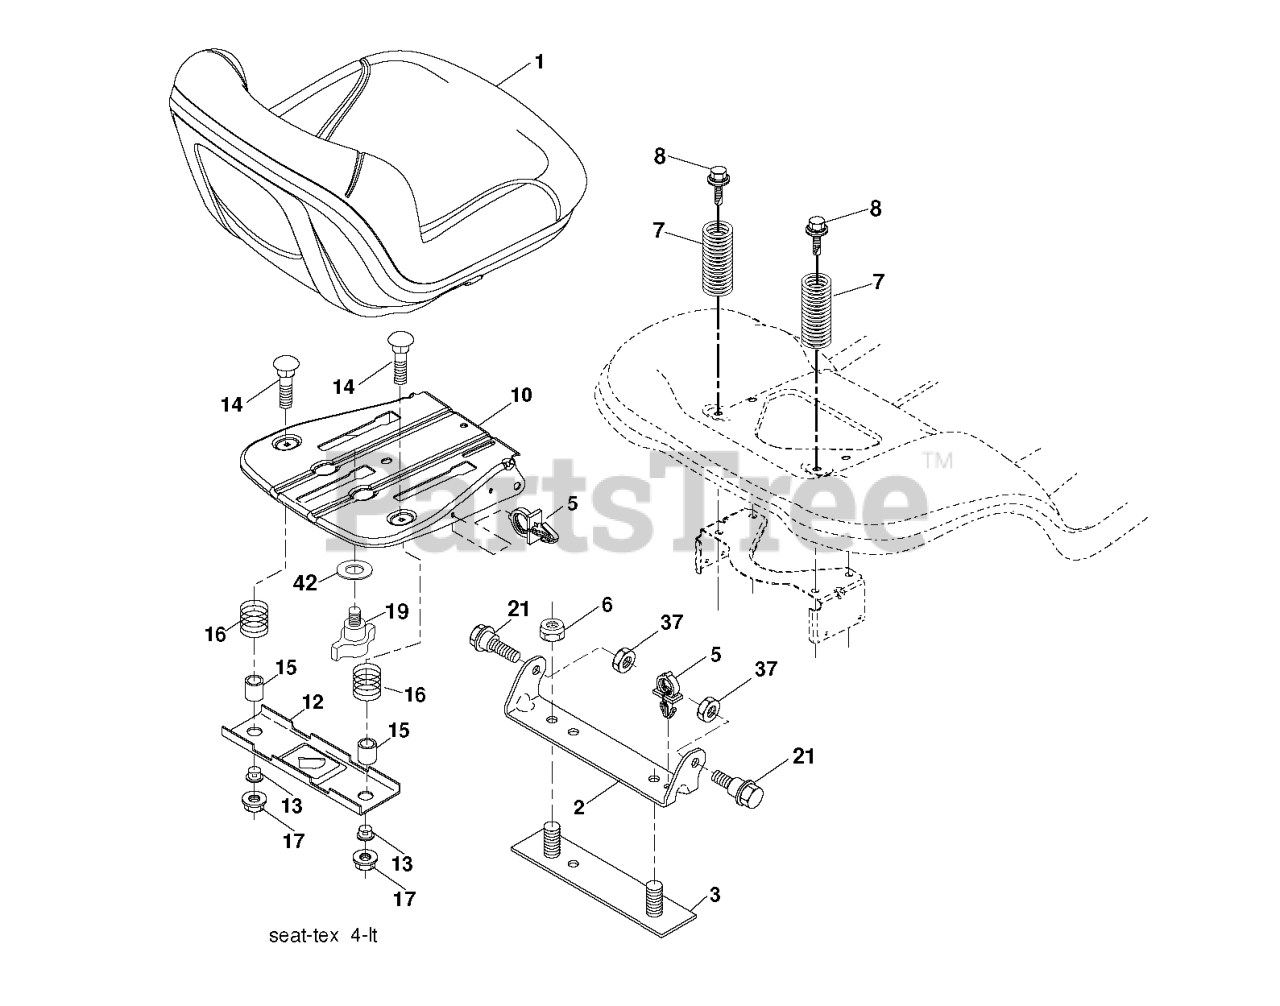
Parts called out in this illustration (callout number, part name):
1	SEAT.TH130.GRY.MILSCO.
2	BRKT.PIVOT.FENDER
3	STRAP
6	NUT
7	SPRING COMPRESSION
8	BOLT.5/16-18UNCX3/4 W/SEMS.BLK
10	PAN.ASM.SEAT.SHORT
12	BRKT.MNT.OPC.SW.SEAT.
14	BOLT.ROUND.HEAD.SQUARE.NECK
15	SPACER SPLIT 28X.96
16	SPRING COMPRESSED
17	NUT T
19	KNOB.SEAT.ADJ.
21	BOLT.SHOULDER.5/16-18
37	NUT.71038.31-18.HEX.NYLOCK
42	WASHER.CUP.SEAT.
